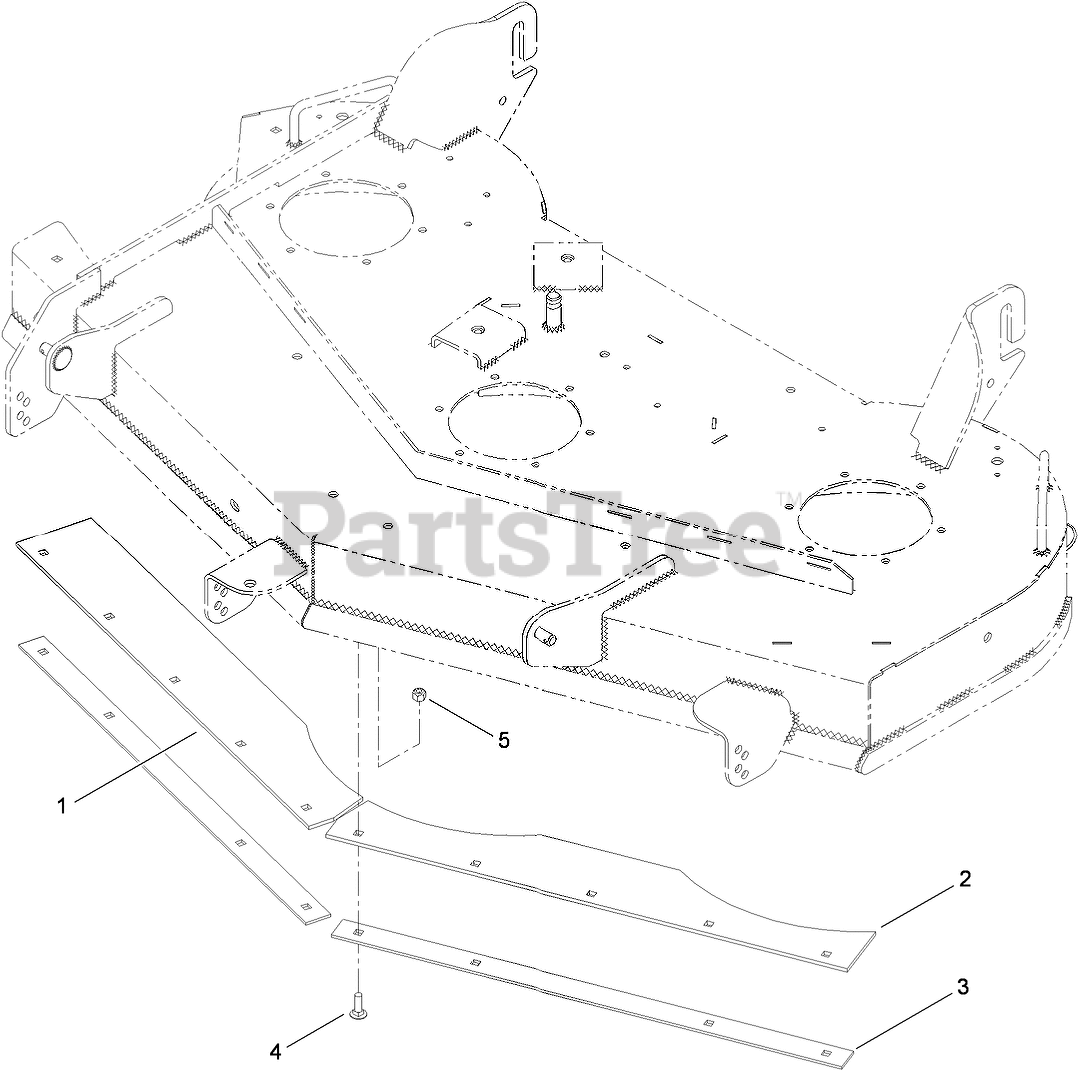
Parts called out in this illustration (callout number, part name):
1	SKIRT-RUBBER, RH
2	SKIRT-RUBBER, LH
3	PLATE-SKIRT
4	BOLT-CARR
5	NUT-LOCK, NI
